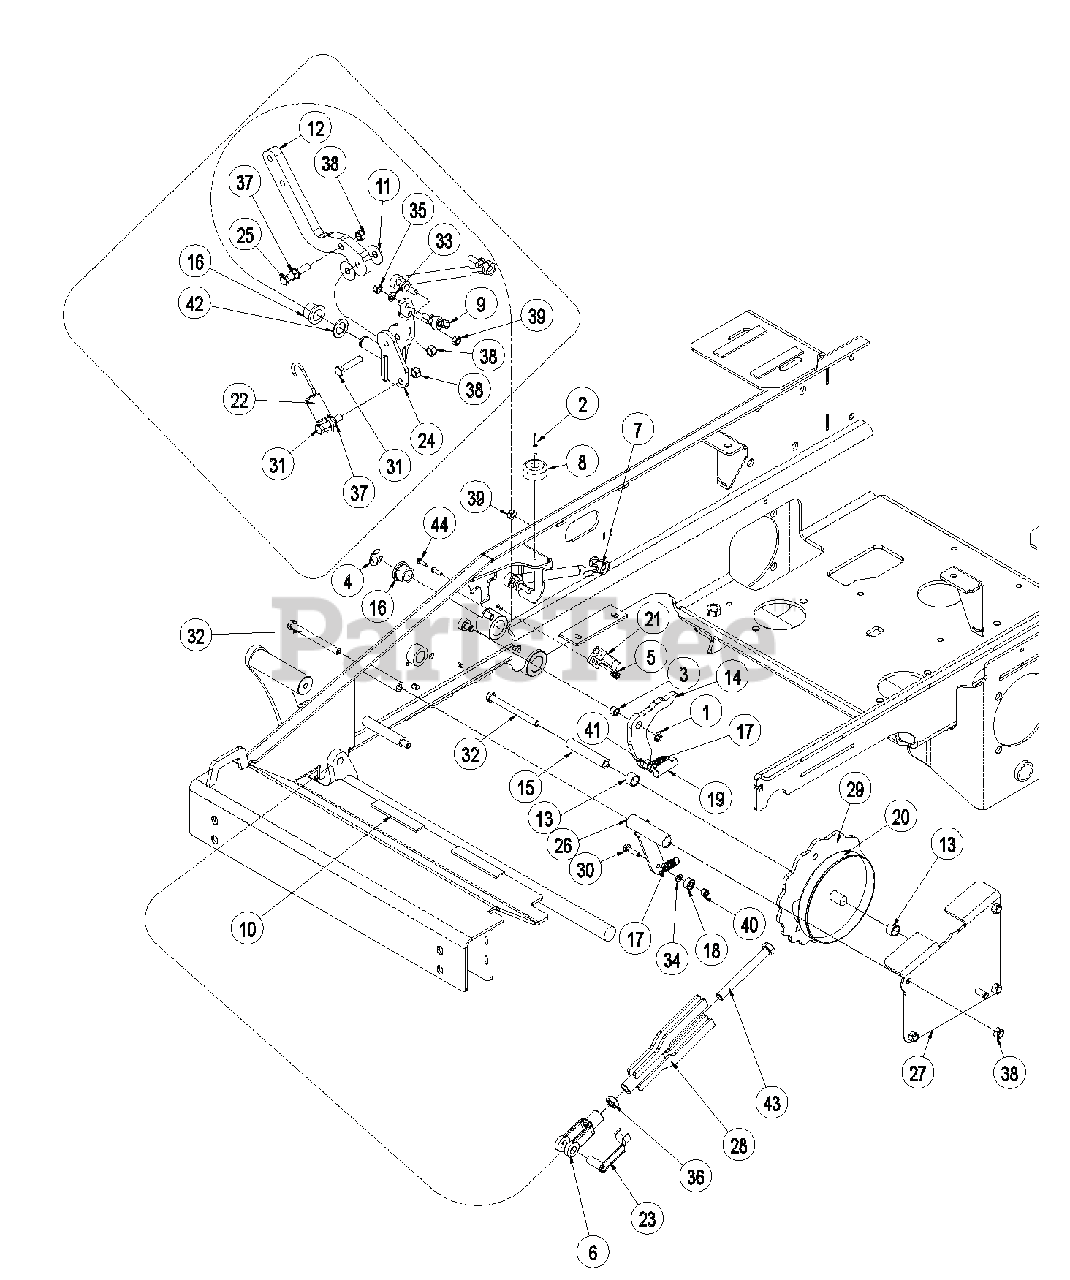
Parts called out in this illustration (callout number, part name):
1	E-RING, .375 X .035 Y
2	RIVET, 3/16 X .500 POP
3	BEARING, SLV .377X.503X.375
4	E-RING, .750 X .050 Y
5	NUT, 10-24 KEPS Y
6	YOKE, ADJUSTABLE 1/2-13 Y
7	DAMPNER, STEERING CONTROL
8	BUMPER, RUBBER .625 X 1.50 DIA
9	BALL JOINT, RH 5/16 FMAL W/STD
10	FOAM, .125 X .750 X 4.00
11	WASHER, .400X1.27X.062 NYLON
12	PLATE, STEERING CONTROL
13	BRG, SLV .627X.752X.500 BRNZ
14	PLATE, BRAKE LEVER
15	SPACER, .63 X .385 X 3.250
16	BRG, FLG .750X1.00X.750 BRNZ
17	SPRING, EXT .500X.041X1.75 SS
18	BRG, BAL .250X.688X.313
19	BALL JOINT, 3/8X24
20	DECAL, HOC INDEX
21	SWITCH, PLUNGER DP - N.O.-N.C.
22	SPRING, EXT .980X.162X4.00 B
23	PIN, CVS SPG 1/2" YOKE SPEC Y
24	WLDT, LH STEERING CONTROL
25	BOLT, 3/8-16X2.00 HEX 5 FLTD Y
26	WLDT, HOC INDEX ARM
27	WLDT, HOC COVER S/O
28	WLDT, HOC LINK
29	ASSY, HOC CAM W/DECAL S/O
30	BOLT, 1/4-20X1.00 HEX 5 Y
31	BOLT, 3/8-16X1.75 HEX 5 Y
32	BOLT, 3/8-16X4.00 HEX 5 Y
33	WASHER, .313 MED SPRG LOCK
34	WASHER, M6 REG FLAT Y
35	NUT, 5/16-24 STD HEX GR5 Y
36	NUT, 1/2-13 JAM GR5 Y
37	LOCKNUT, 3/8-16 WHIZ Y
38	LOCKNUT, 3/8-16 CROWN Y
39	LOCKNUT, M8-1.25 CROWN Y
40	LOCKNUT, 1/4-20 NYLOC Y
41	NUT, 3/8-24 STD HEX Y
42	BUSHING, MACH .750X1.25X.075 Y
43	BOLT, 1/2-13X4.50 HEX 8 Y
44	SCREW, 10-24X.625 PAN PHL MACY
